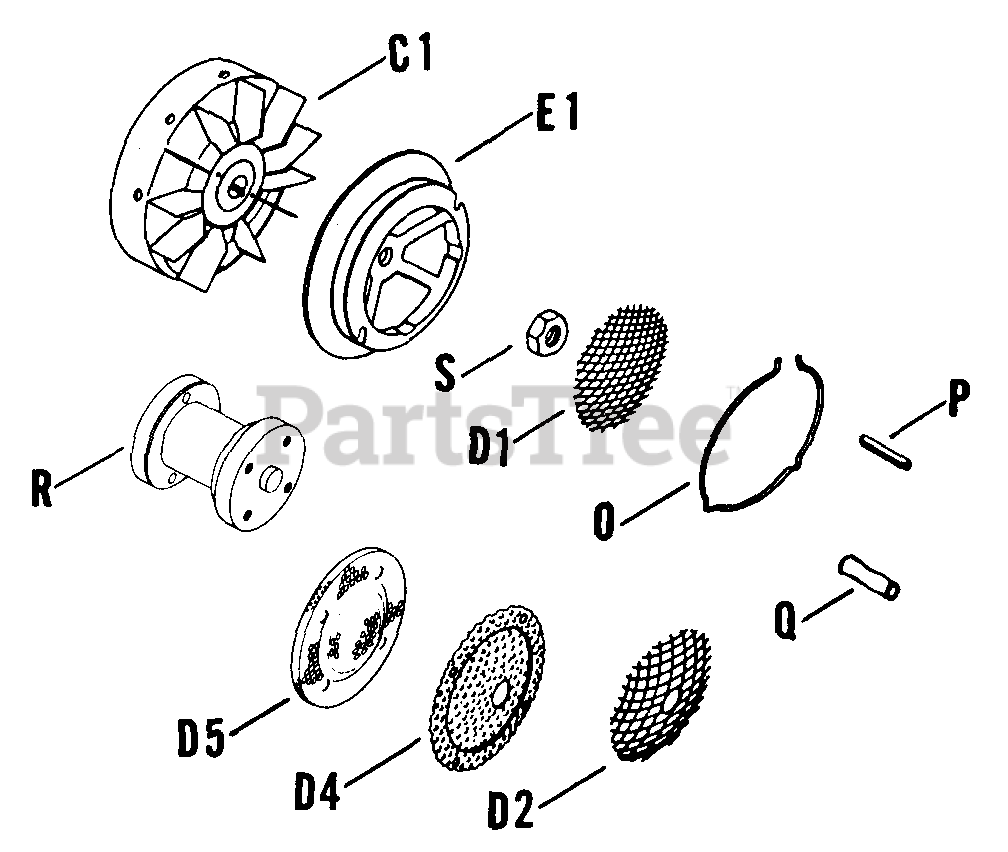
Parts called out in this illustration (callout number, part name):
C1	FLYWHEEL - DISCONTINUED
P	KEY - USE X-286-17
S	NUT - USE 25 100 02
